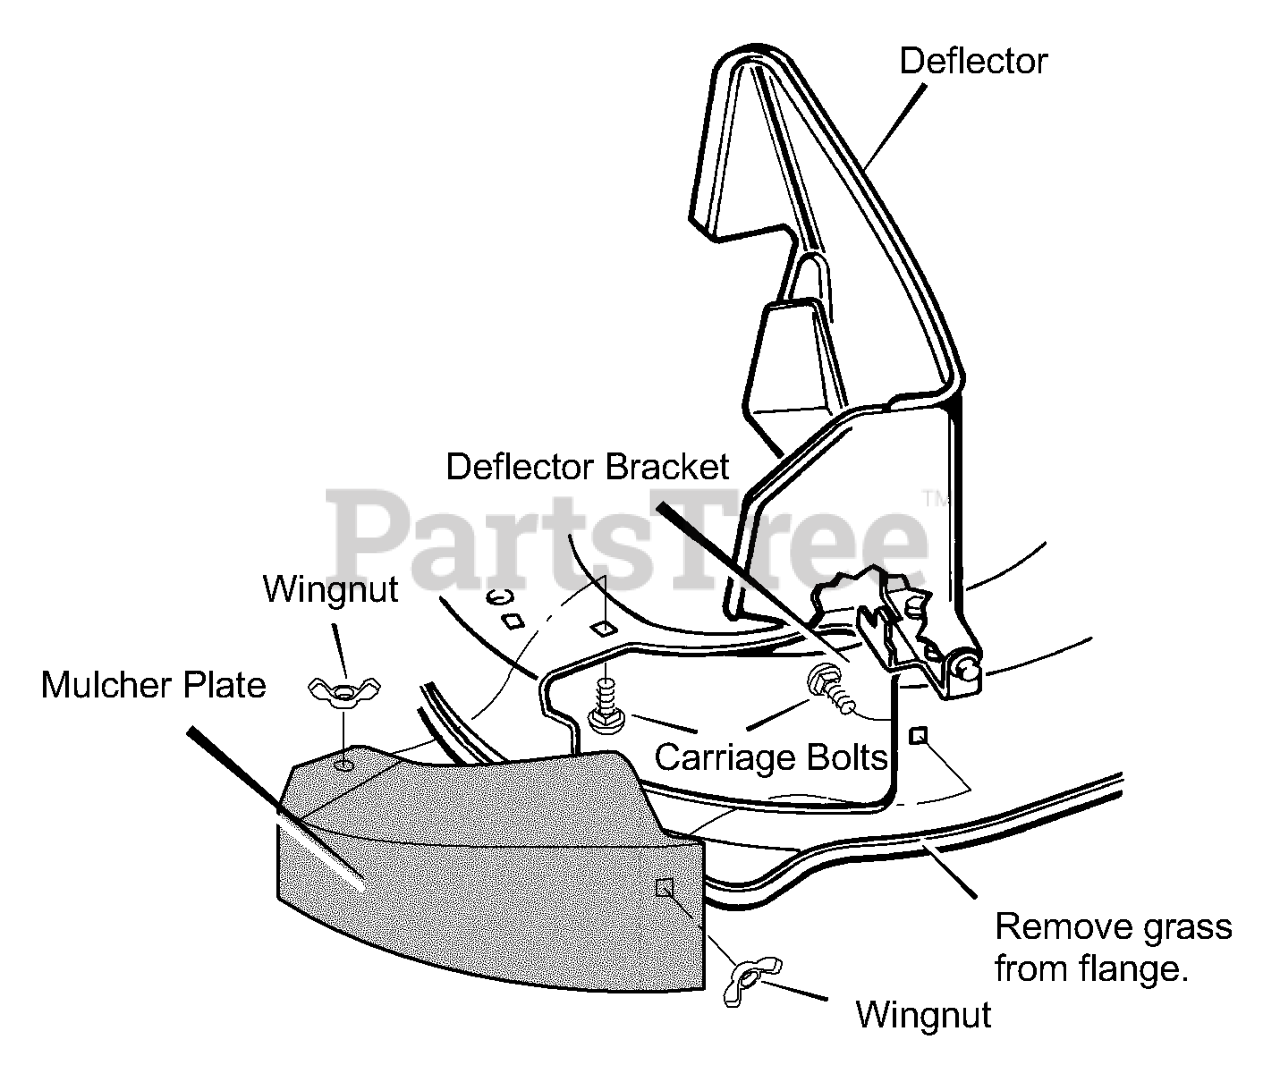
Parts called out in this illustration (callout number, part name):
1	Mulcher Plate
2	Wingnut
3	Carriage Bolt
